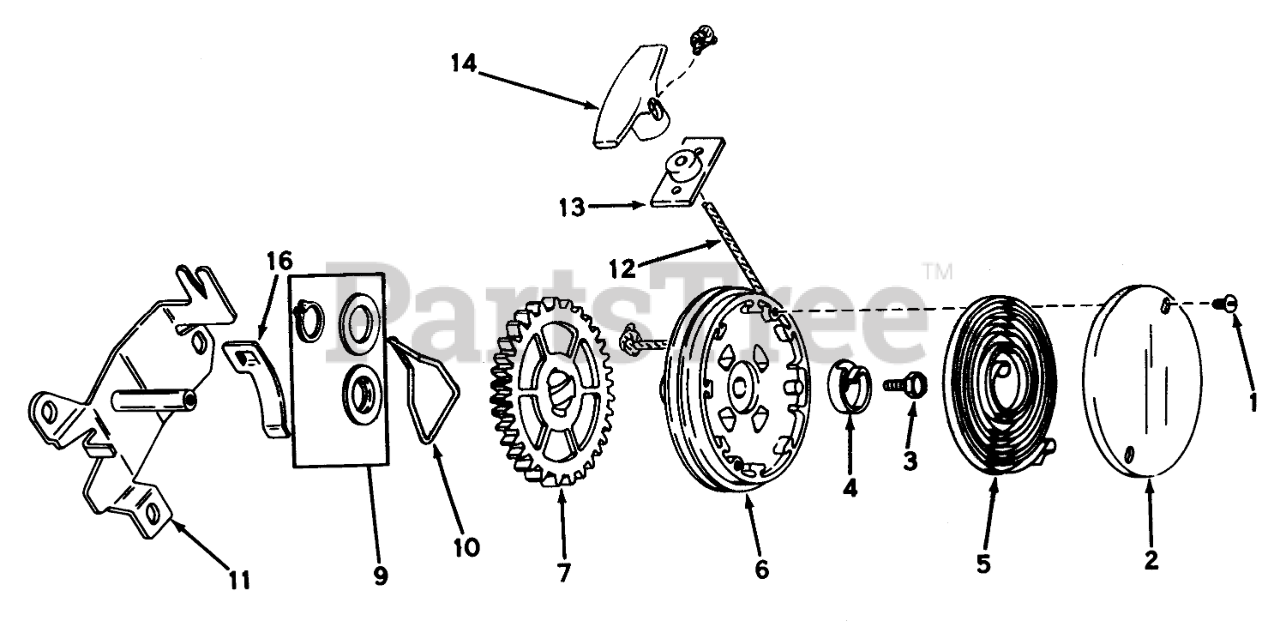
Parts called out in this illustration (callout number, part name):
1	Screw, Cover
2	Cover, Spring
3	Screw, Hex Washer Head
4	Hub Spring
5	Spring, Rewind
6	Pulley Assy. (Incl. #9)
7	Gear
9	Kit, Thrust Wash. & Snap Rg.
11	Bracket Assy. Mounting
12	Rope, Starter
13	Bracket Assy.
14	Handle-Starter
16	Clip Rope
